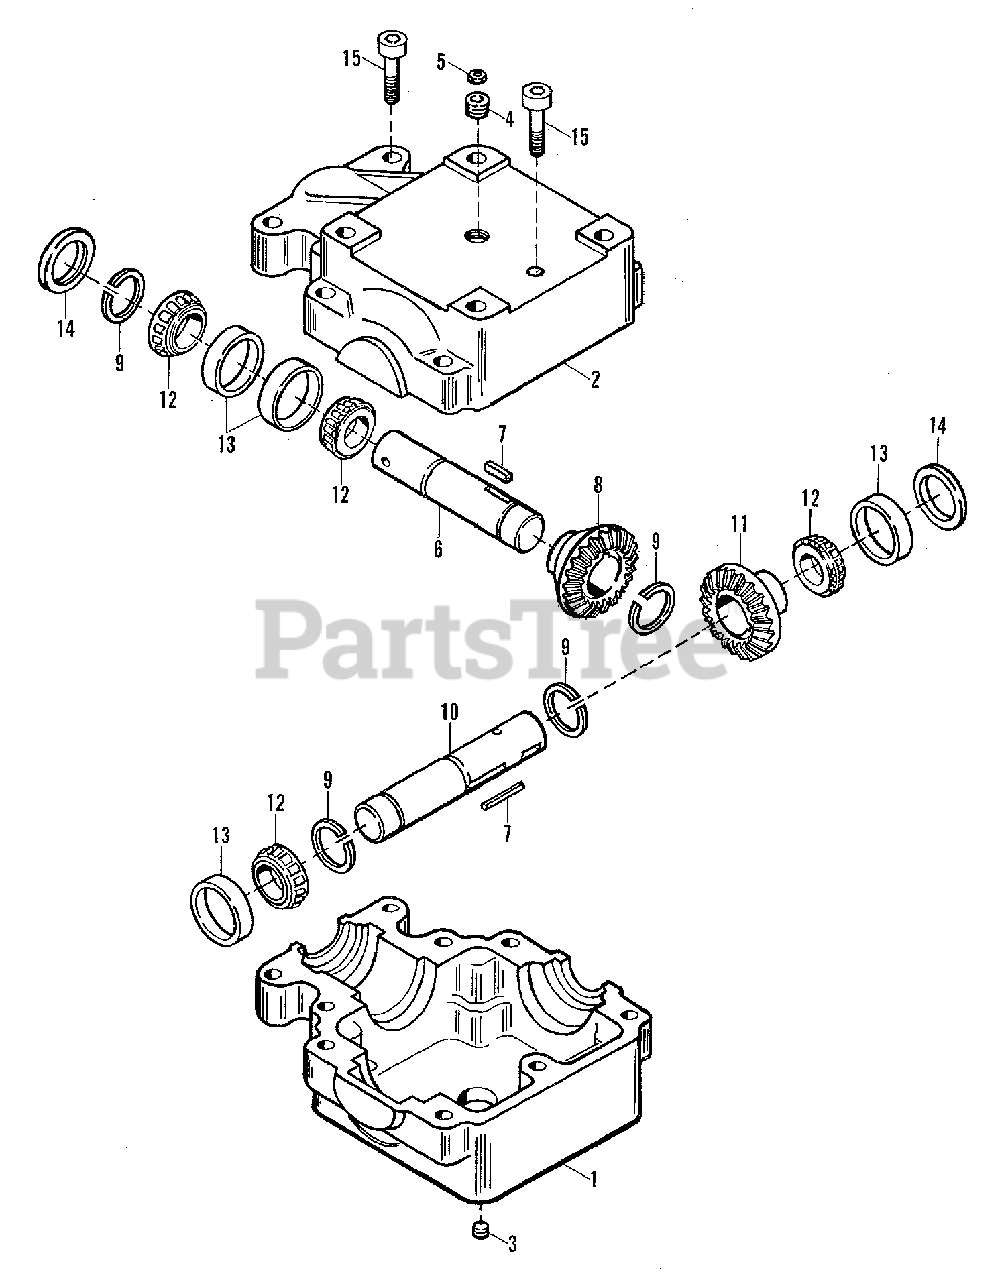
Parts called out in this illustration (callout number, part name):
1	HOUSING, Half (Threaded Holes)
2	HOUSING, Half (Thru Holes)
4	BUSHING, Pipe Adapter
5	PLUG, Pressure Relief (5 P.S.I.)
6	SHAFT, Pinion
7	KEY, Straight, 1/4 x 1/4 x 1-1/8
8	GEAR, Pinion (20T)
9	RING, Retaining
10	SHAFT, Cross
11	GEAR, (30t)
12	CONE, Bearing
13	CUP, Bearing
15	CAPSCREW, Socket Head, 3/8NC x 2-1/4, Gr. 8
